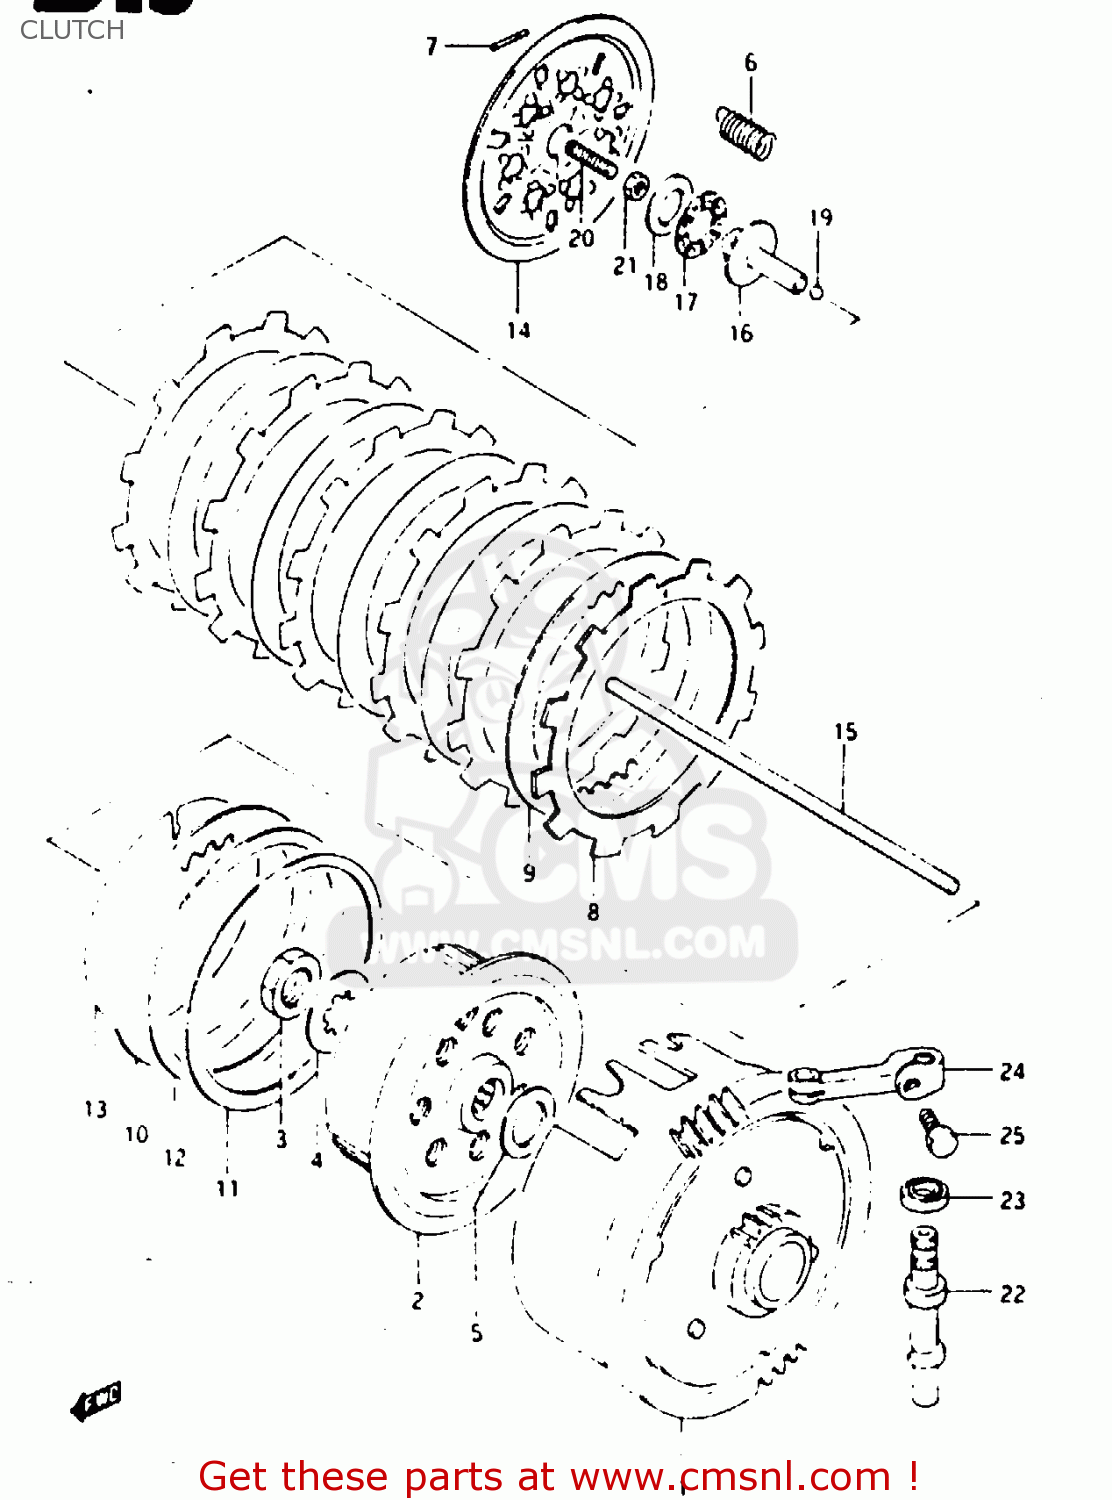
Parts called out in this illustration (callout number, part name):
1	GEAR, PRIMARY DRIVEN
2	HUB, SLEEVE
3	NUT
4	WASHER,LOCK
5	WASHER
6	SPRING
7	PIN(2.5X19.8)
8	PLATE,CLUTCH DRIVE
9	PLATE,CLUTCH DRIVEN (NAS)
10	PLATE,CLUTCH DRIVEN(T:2.0) (NAS)
11	SEAT,WAVE WASHER
12	WASHER
13	RING,STOPPER
14	PLATE,CLUTCH PRESSURE
15	ROD,CLUTCH PUSH
16	PIECE,CLUTCH PUSH
17	BEARING(15X28X2)
18	WASHER
19	BALL
20	SCREW(6X25)
21	NUT 6MM
22	SHAFT,CLUTCH RELEASE C
23	OIL SEAL
24	ARM, RELEASE
25	BOLT
